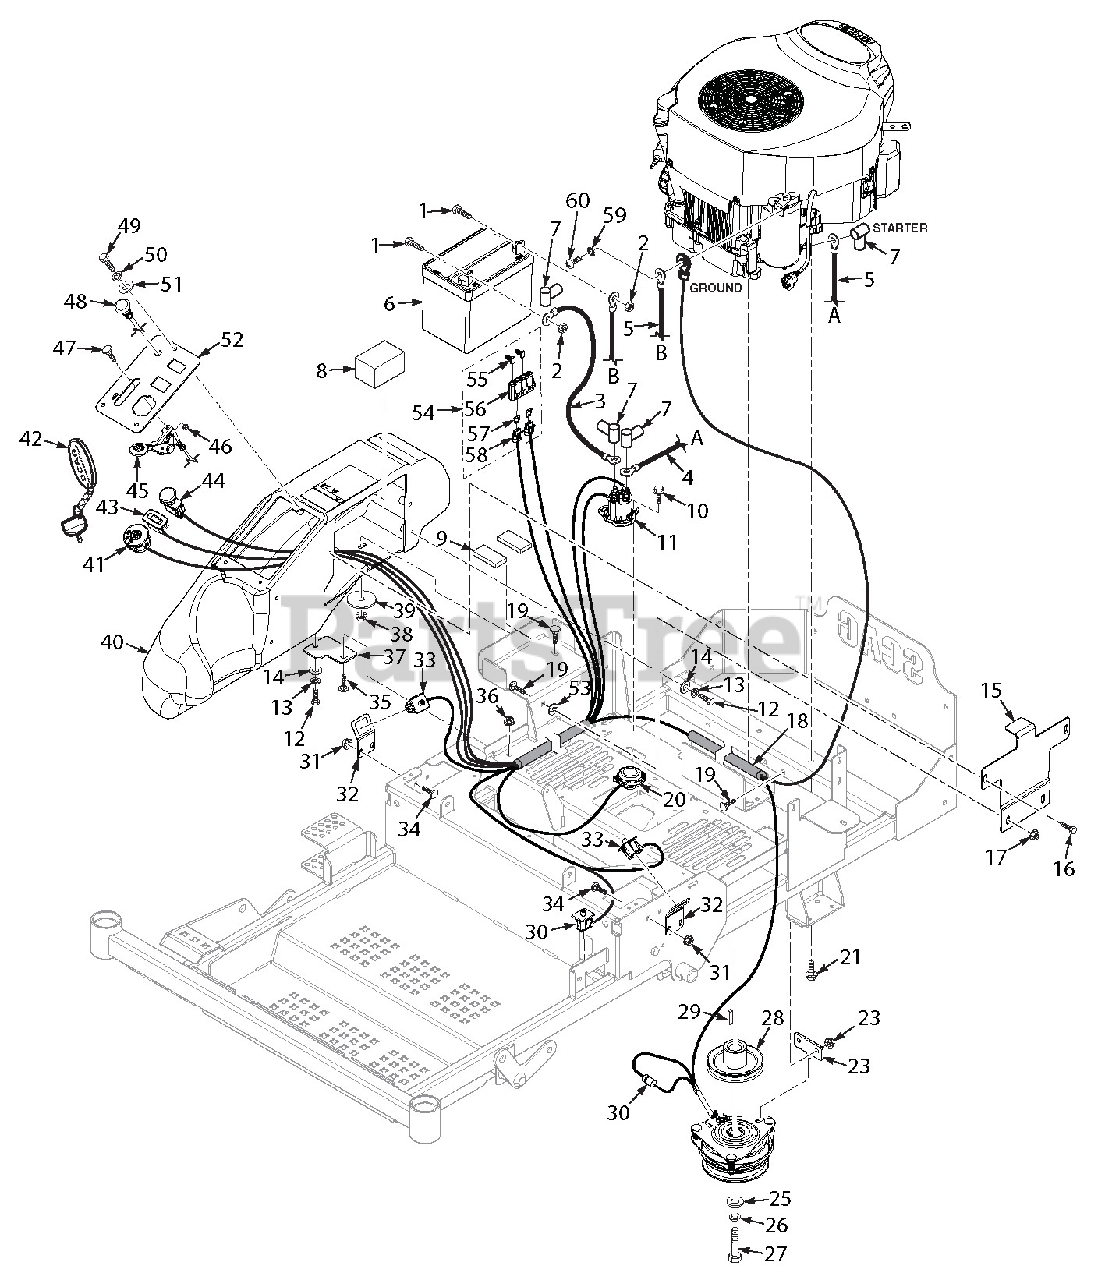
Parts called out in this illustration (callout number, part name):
1	Bolt, Hex Head 1/4-20 x 1/2"
2	Nut, 1/4-20 UNC
3	Cable, Battery - 18" Red
4	Cable, Battery - 25" Red
5	Cable, Battery - 36" Black
6	Battery, 12v - 230CCA
7	Rubber Boot
8	Pad, Battery - Rubber
9	Pad, Battery - Rubber
10	Screw, 1/4-20 x 3/4" Shakeproof
11	Solenoid, Sealed
12	Bolt, Hex Head 5/16-18 x 3/4"
13	Lockwasher, 5/16"
14	Flatwasher, 5/16-.375 x .875 x .083
15	Battery Hold Down
16	Bolt, Hex Head 5/16-18 x 1/2" Serrated Flange
17	Nut, 5/16-18 Elastic Stop
18	Wire Harness
19	Bolt, Carriage 5/16-18 x 3/4"
20	Switch, Double Pole - Twist
21	Screw, Hex Head 3/8-16 x 1-1/4" Self Tap
22	Nut, 5/16-18 Elastic Stop
23	Plate, Anti-Rotation
24	Clutch, GT1
25	Flatwasher, 7/16-.496 x 1.75 x .25
26	Lockwasher, 7/16"
27	Bolt, Hex Head 7/16-20 x 3" w/Patch
28	Pulley, 4-1/2" Dia. - 1" Bore
29	Key, 1/4 x 1/4 x 1-1/4"
30	Diode (part of wire harness)
31	Nut, 1/4-20 Flange Elastic Stop
32	Bracket, Switch
33	Switch, Double Pole - Plunger
34	Bolt, Carriage 1/4-20 x 3/4"
35	Bolt, Carriage 5/16-181 x 1"
36	Nut, 5/16-18 Serrated Flange
37	Mounting Bracket, Fuel Tank Front
38	Nut, 5/16-18 Serrated Flange
39	Flatwasher, 3/8-.406 x 2.25 x .188
40	Console Tank, SZL
41	Ignition Switch
42	Key Fob Assembly
42	Key w/Shroud Only
43	Hourmeter
44	Switch, PTO
45	Throttle Cable
46	Nut, #10-24 Elastic Stop
47	Bolt, Carriage #10-24 x 1/2"
48	Choke Control
49	Bolt, Hex Head 1/4-20 x 1/2"
50	Lockwasher, 1/4"
51	Flatwasher, 1/4-.312 x .750 x .065
52	Instrument Panel w/Decal
53	Nut, 5/16 Push-On
54	Double Fuse Assembly
55	Clip, Wire
56	Cover, Double
57	Fuse, 20 Amp
58	Fuse Holder
59	Lockwasher, 5/16" Ext.
60	Screw, M6-1.00 X 16 Shakeproof
